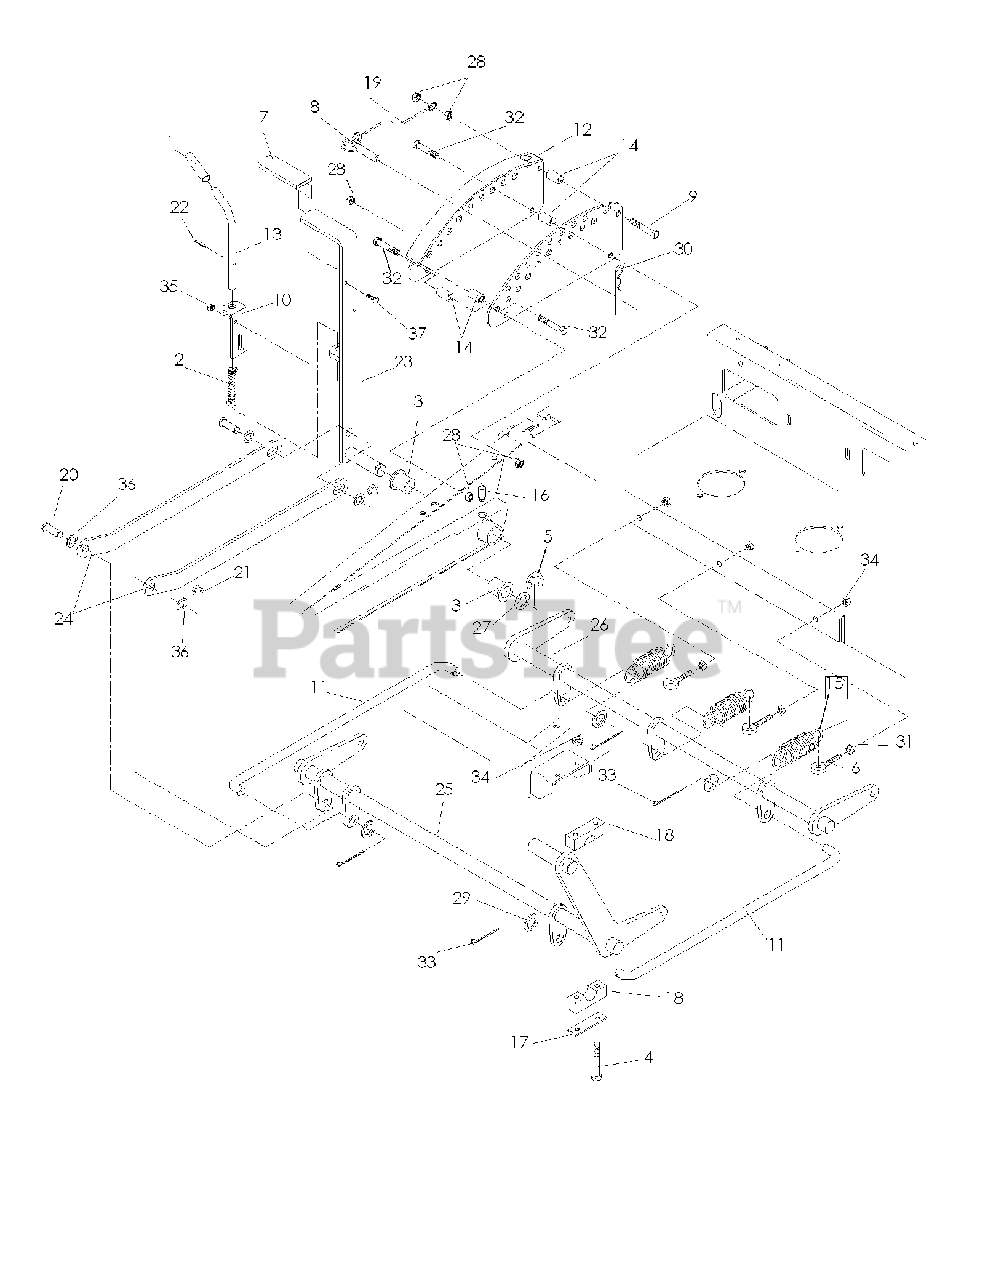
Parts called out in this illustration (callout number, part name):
3	BUSHING, FLANGED
4	HCS 5/16C X 2-3/4
5	E-RING 7/8
6	EYEBOLT, RH
8	HITCH PIN
9	SCREW 3/8C X 2 3/4 HEX CAP
10	PIN MT, UPPER
11	CONNECTING LINK
12	PLATE, HEIGHT
14	DECK LIFT SPACER
15	DECK LIFT SPRING
16	GREASE ZERK LONG
17	REINFORCEMENT BAR
18	PILLOW BLOCK
19	LANYARD
20	CLEVIS PIN
21	E-RING 5/8
23	LIFT LEVER WELDMENT
24	STRAP, LIFT
25	SHAFT, LIFT, FRONT
26	SHAFT, LIFT, REAR
27	BSHG .875 X 1.375 X .074 ZD
28	NUT 3/8-16 NYLOC
29	WASHER 5/8 FLAT
30	HAIRPIN #4
31	NUT 5/16C WHIZ
32	HCS 3/8C X 2 1/4
33	COTTER PIN
34	NUT 5/16 NYLOC
35	NUT 1/4C CENTER LOCK
36	BUSHING
37	HCS 1/4C X 3/4 HCS
